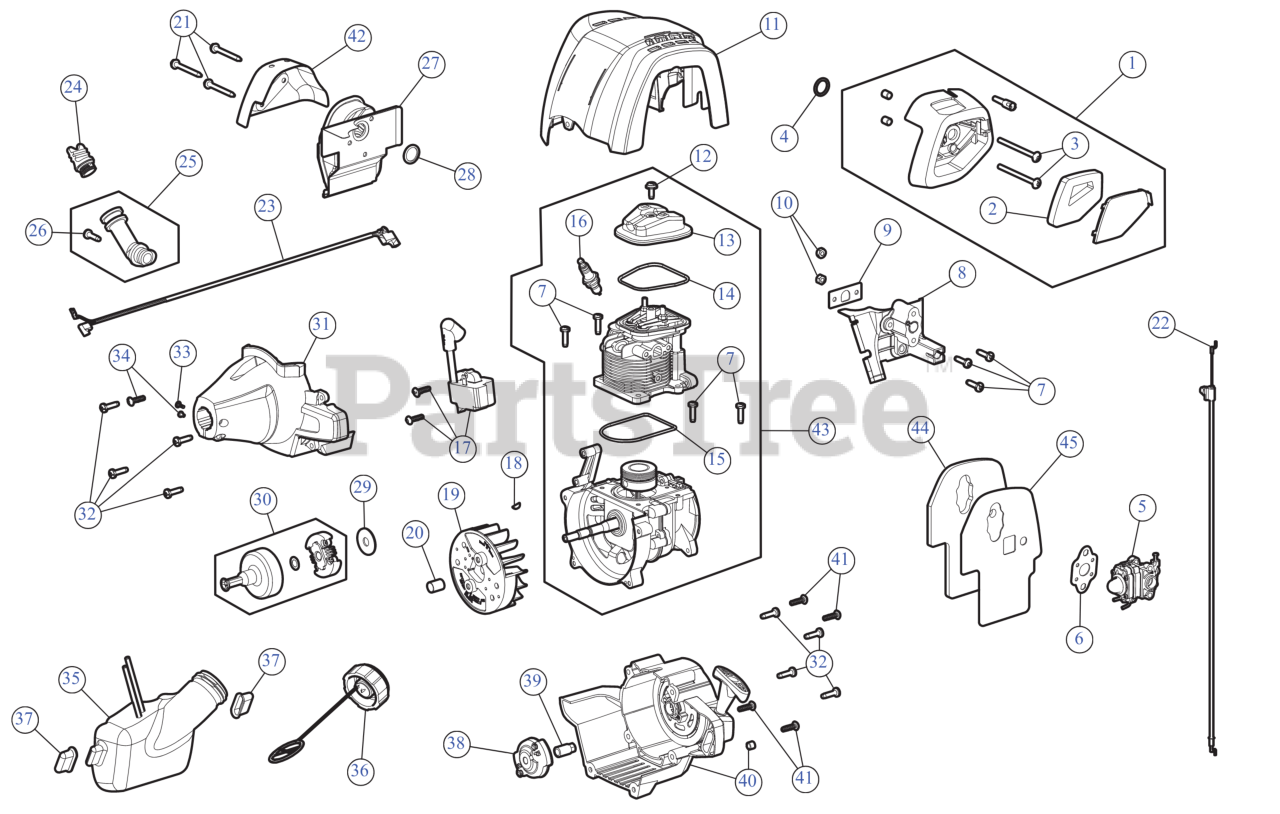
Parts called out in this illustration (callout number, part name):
1	AIR CLEANER ASSEMBLY
2	AIR FILTER
3	SCREW 10-32X3
5	CARBURETOR ASSEMBLY
6	CARBURETOR GASKET
7	SCREW, M5 x 18.7MM
8	INSULATOR
9	INSULATOR GASKET
10	NUT 10-32
11	TOP ENGINE COVER
12	SCR, VALVE COVER
13	ROCKER COVER
14	O-RING
15	O-RING CYL AC5
16	SPARK PLUG 4 CYCL
17	MODULE MA-95
18	WOODRUFF KEY #403-.125 x .375
19	FLYWHEEL W/KEY
20	SPACER .591"
21	SCREW M5 x 44MM
22	THROTTLE CABLE
23	WIRE LEAD AC5
24	OIL PLUG ASSEMBLY
25	OIL FILL TUBE
26	SCR, M5 x 15.8MM
27	MUFFLER ASSEMBLY AC5.1
28	GASKET/MUFFLER
29	WASH, CLUTCH O.D. 1.155 +/- .0
30	SMALL CLUTCH ASSEMBLY W/SMALL DRUM
31	CLUTCH COVER
32	SCREW M5-0.8 x 19
33	SCREW, 8-32 x .312 P
34	SCREW:CLMPNG W/NUT
35	FUEL TANK ASSEMBLY
36	FUEL CAP ASSEMBLY
37	FUEL TANK PADS
38	PAWL ASSEMBLY AC5
39	ELECTRIC START ADP
40	STARTER HOUSING
41	SCREW 8-16 x 3/4
42	MUFFLER SHLD
43	SHORT BLOCK
44	HEAT SHLD CARB AC5
45	CARBURETOR GASKET
